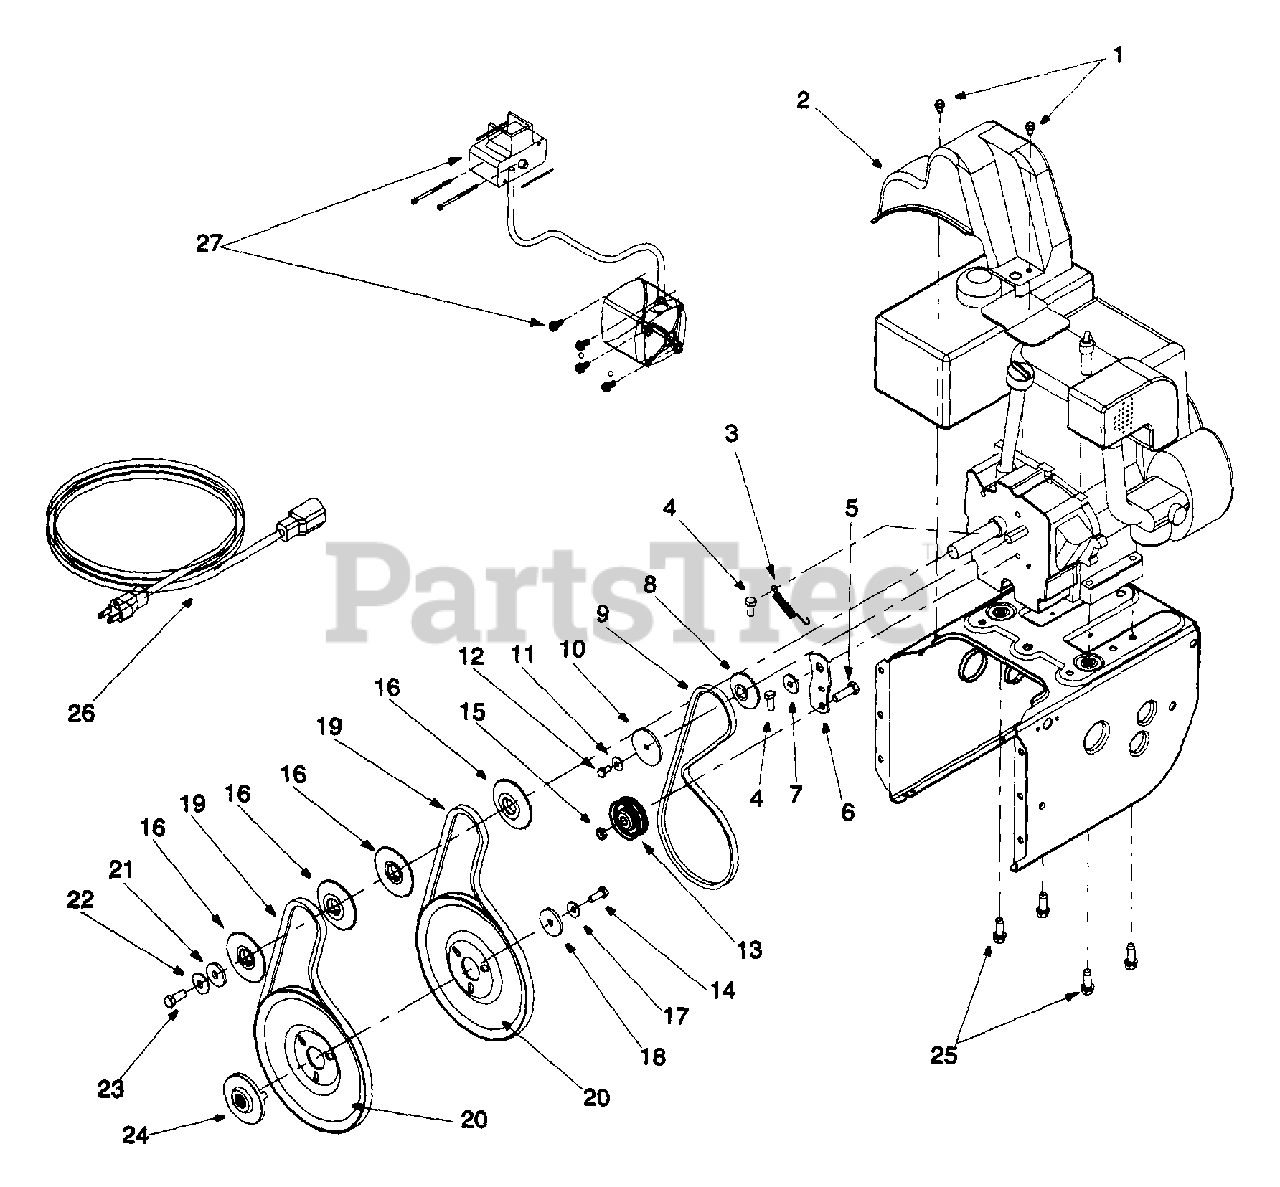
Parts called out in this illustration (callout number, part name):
1	Hex Washer Screw 1/4-20 x .50
2	Belt Cover
3	Extension Spring
4	Hex Screw 5/16-24 x .75
5	Hex Cap Screw 3/8-16 x 1.25
8	Pulley Half
9	V-Belt
10	Pulley Half
11	Bell Washer
12	Hex Cap Screw 1/4-28 x .50
13	Flat Idler
14	Lock Hex Cap Screw 5/16-24
15	Lock Jam Nut 3/8-16
16	Pulley Half
17	Bell Washer
18	Flat Washer
19	Belt
20	Auger Pulley
21	Flat Washer 3/8 x 1.25 OD
22	Bell Washer
23	Hex Cap Screw 3/8-24
24	Adapter Pulley
25	Hex Screw 3/8-16 x 1.0
26	Extension Cord
27	Electric Start
